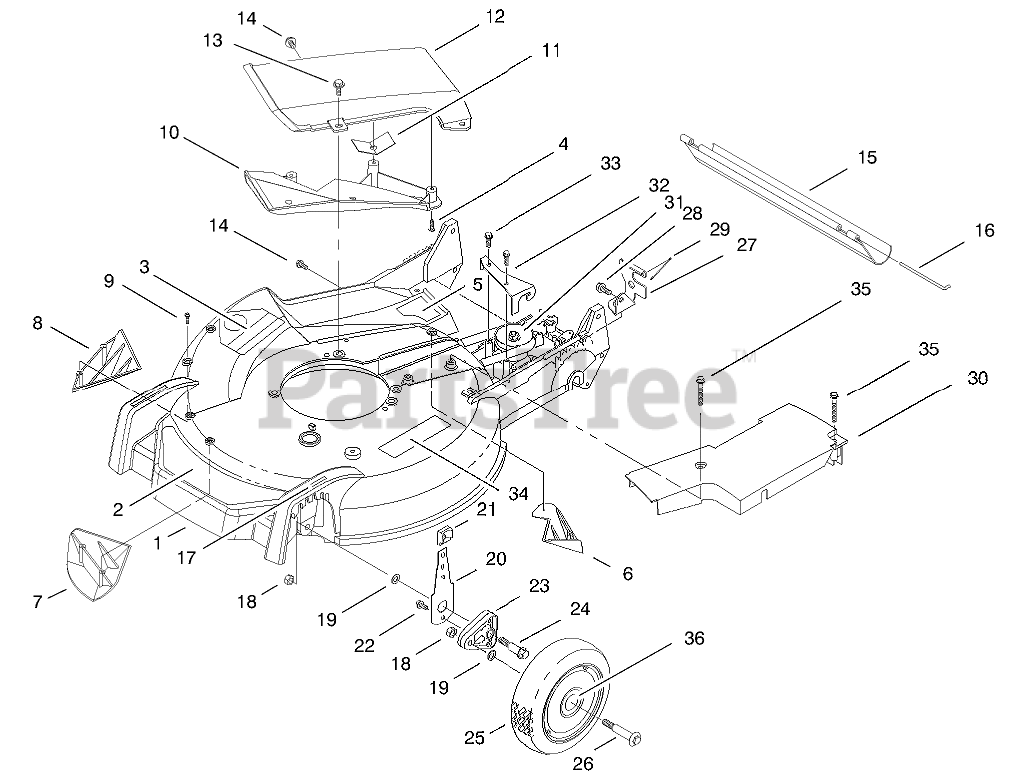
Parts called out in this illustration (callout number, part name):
1	Housing-Rwd (Incl. Ref. #3, 5-9, 17, & 34)
2	DECAL - DECK
3	DECAL-DANGER
4	Screw-PPH
5	DECAL - DANGER
6	KICKER-REAR
7	KICKER-FRONT
8	KICKER-RH
9	SCREW-PPH
10	Deflector-Recycler
11	Guard-Cover
12	Cover Assembly (Incl. Ref. #5, &10-11)
13	SCREW-HWH
14	SCREW AND WASHER ASM
15	SHIELD-TRAILING
16	ROD-SHIELD
17	DECAL - HOC
18	NUT-LOCK
19	WASHER
20	FRONT SPRING ARM ASM
21	KNOB-ARM
22	SCREW-HWH
23	ARM-PIVOT, FRONT
24	BOLT-SHOULDER
25	WHEEL ASM
26	BOLT-WHEEL
27	Bracket-Adj. Trac
28	SCREW-HWHTF
29	RETAINER-CABLE
30	COVER - BELT
31	GEARCASE ASM
32	Bracket-Guide
33	SCREW-HWHTF
34	DECAL-WARNING
35	SCREW-HHFTF
36	BUSHING
